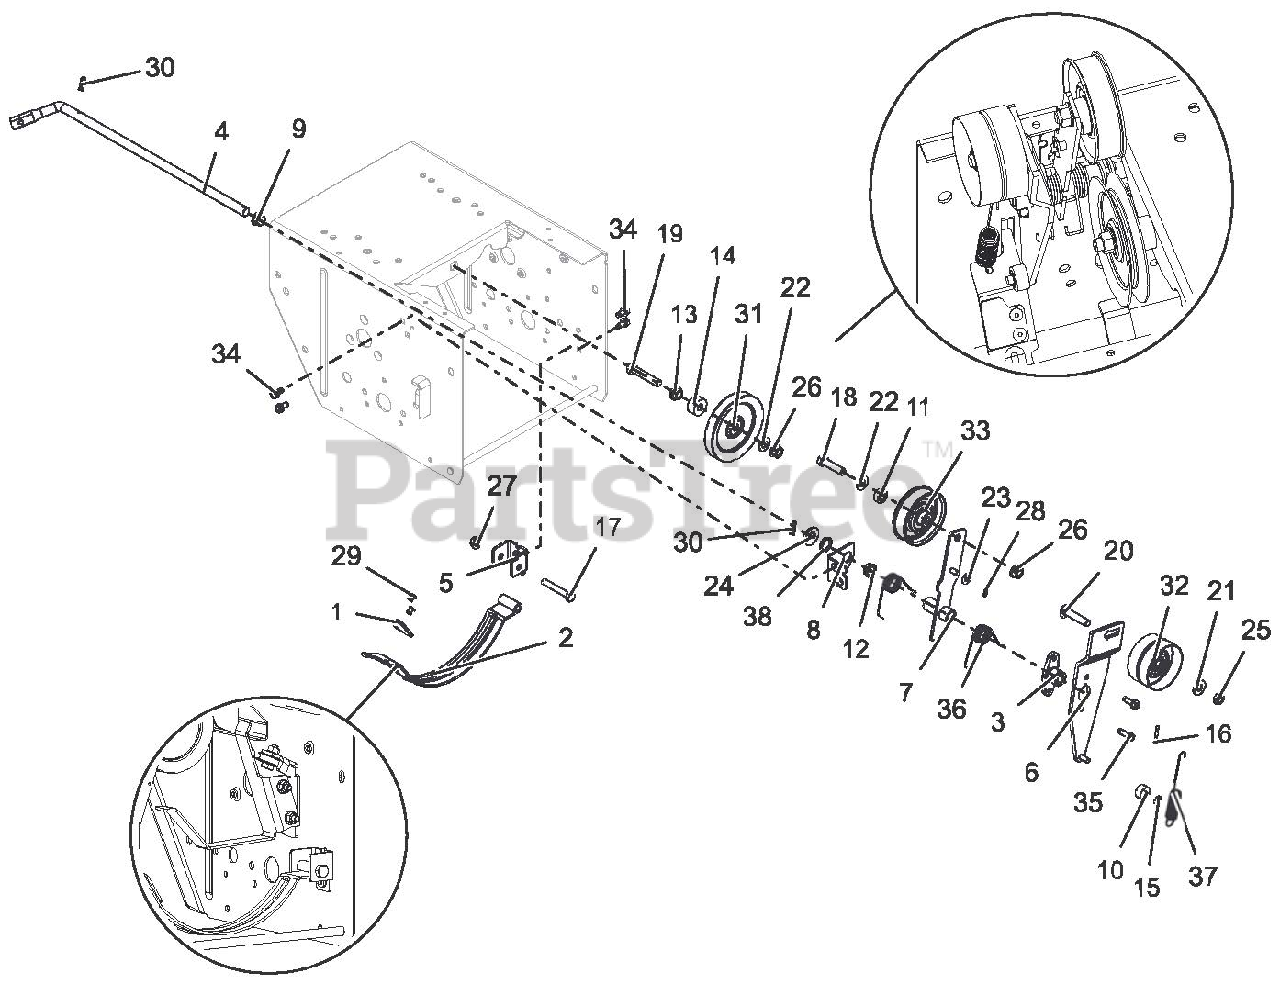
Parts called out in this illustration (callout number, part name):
1	PAD, BRAKE
2	ARM, BRAKE-ATTACHMENT
3	HUB, BRAKE ARM
4	ARM, ATTACHMENT
5	PIVOT, BRAKE
6	ARM, IDLER-ATTACHMENT
7	ARM, TRACTION CLUTCH
8	BRACKET, SUPPORT
9	BUSHING, POLYLINER-.50 SPLIT
10	BSHG,SLV .265 X .625 X .375
11	SPCR, BRG .315X.500X.358X.281
12	BSHG,FLANGE .500X.625X.270X.75
13	BSHG, FLANGE .391X.56X.313X.75
14	BSHG,POCKET .391X.570X1.0X.450
15	RG-RTNG-EXT .250X.010
16	PIN-ROLL .125X1.00
17	@BLT-HEX .31-18X2.00 GR5 YWZC
18	@BLT-HEX .38-16X1.50 GR5 YWZC
19	@BLT-HEX .38-16X2.00 GR5 YWZC
20	@BLT-RHDSSQNK .38-16X1.75 G5YZ
21	@WSHR-FL-STL.38X.875X.083 YWZC
22	@WSHR-FL-STL.406X.812X.065 YWZ
23	@WSHR-FL-STL.281X.62X.065 YWZC
24	@WSHR-FL-STL.531X1.06X.095YWZC
25	@NUT-LK-CTR-JAM .375-16 YWZC
26	@NUT-LK-TOP-FLG .38-16 YWZC
27	@NUT-LK-TOP-FLG .31-18 YWZC
28	PIN-HAIR INT .06X.18X.77
29	RVT-POP .187 YZ
30	CLIP, SPRING
31	SHV, .38"ID X 4.00"OD V-IDLER
32	IDLER, FLAT-2.75 OD X .375 ID
33	IDLER, FLAT - 3.05" X .75"
34	SCR-TAP .25-20X.50 HWH TR YWZ
35	SCR-TAP-PM .25-20X.75 TR YWZ
36	SG-TORS .067X.88
37	SG-TENS .056X.60X4.40
38	WAVE SPRING .600X.875X.25FH
